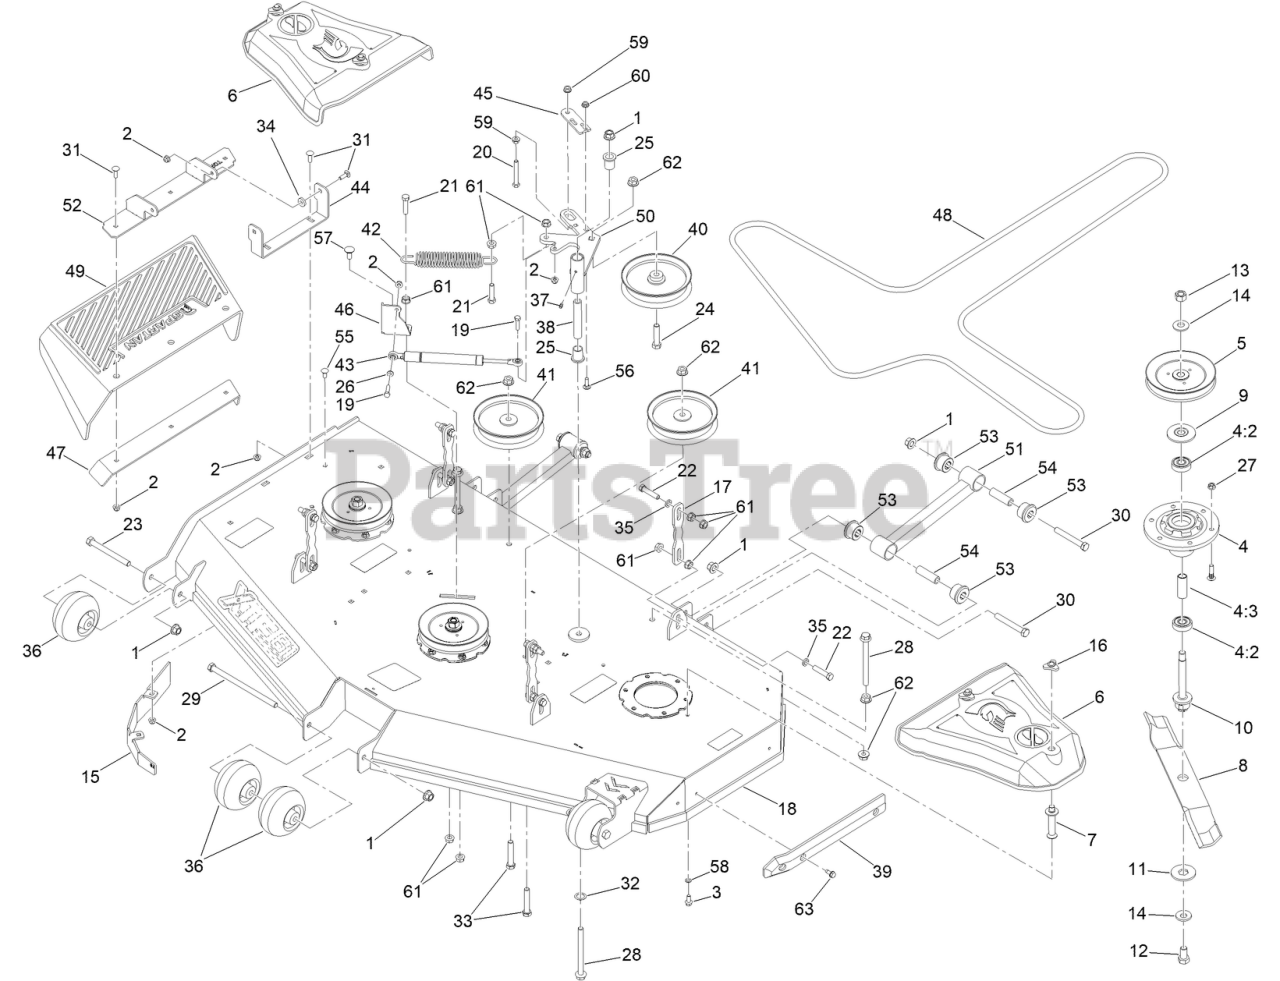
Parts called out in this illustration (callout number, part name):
1	NUT-LOCK
2	NUT-HF, NI
3	SCREW-HHF
4	SPINDLE ASM 5IN DECK
4:2	BEARING
4:3	SPACER, BEARING
5	PULLEY
6	COVER-BELT
7	PIN-BELT COVER
8	BLADE-ROTARY
9	GUARD-BEARING TOP 0.673IN
10	SHAFT - SPINDLE
11	WASHER-HEX
12	M16X1.5-30MM C10.9 HEX BOLT
13	M16X1.5 C8.8 HEX NUT
14	M16 SPRING WASHER (39MMOD/ 3.9MM THK)
15	BAFFLE-WIPER
16	NUT-KNOB
17	HANGER-DECK PAINTED GREY
18	ASM-DECK W/ DECALS
19	SCREW-HH
20	SCREW-HH
21	SCREW-HH
22	SCREW-HH
23	SCREW-HH
24	SCREW-HH
25	3/4IN ID X15/16IN OD X 1-1/8IN FLNG BUSH
26	.312IDX.625ODX.062 THK THRUST BRG OI BRZ
28	1/2-13 X 5-1/2 HEX FLANGE BOLT GR 8 ZY
29	1/2-13 X 8-1/2 HEX C/S GR 2 ZINC YELLOW
30	1/2-13 X 3-3/4 HEX C/S (GR.5) ZC/YEL
31	5/16-18 X 1 CARRIAGE BOLT GR 8 YZ
32	.767IDX1.125ODX.016 THK TRIP WV WASHER
33	1/2-13 X 2-3/4 HEX FLANGE BOLT (GR.8) YZ
34	.312 ID X .875OD X .1875 THK F/W NYL
35	.443 ID X .749 OD X .125 THK NYLON BLACK
36	MWR ANTI-SCALP WHL W/O GREASE FITTING
37	1/4IN DRIVE TYPE GREASE FITTING YZ
38	MWR INNER IDLER SPACER
39	MWR NYLON DECK GUARD
40	6-3/4IN IDLER PULLEY 7/16IN SPACER ASM
41	6-3/4IN IDLER PULLEY 15/16IN SPACER ASSY
42	MWR DECK SPRING
43	IDLER GAS SPRING
44	MWR CHUTE MTG BRKT PAINTED
45	DECK IDLER PULLEY BELT RETNR BRKT PAINT
46	DECK BELT IDLER DAMPER MTG BRKT PAINTED
47	RZ MWR DECK CHUTE HNGE BACKR BRKT PAINT
48	61 DECK BELT
49	RZ MWR RUBBER DISCHARGE CHUTE
50	MWR DECK IDLER PULLEY ARM ASSY PAINT
51	RZ MWR DECK STABILIZER ASSY PAINTED
52	2020 RZ MWR DECK CHUTE HINGE ASSY PAINT
53	RED A80 SUSP BUSHING
54	UTV A-ARM BUSHING SLEEVE
55	BOLT-CARR
56	BOLT-CARR
57	SCREW-CARR
58	WASHER-LOCK
59	NUT-HHF, WHIZ
60	NUT-HF
61	NUT-HF
62	NUT-HHF
63	SCREW-HWH, THREAD CUT
